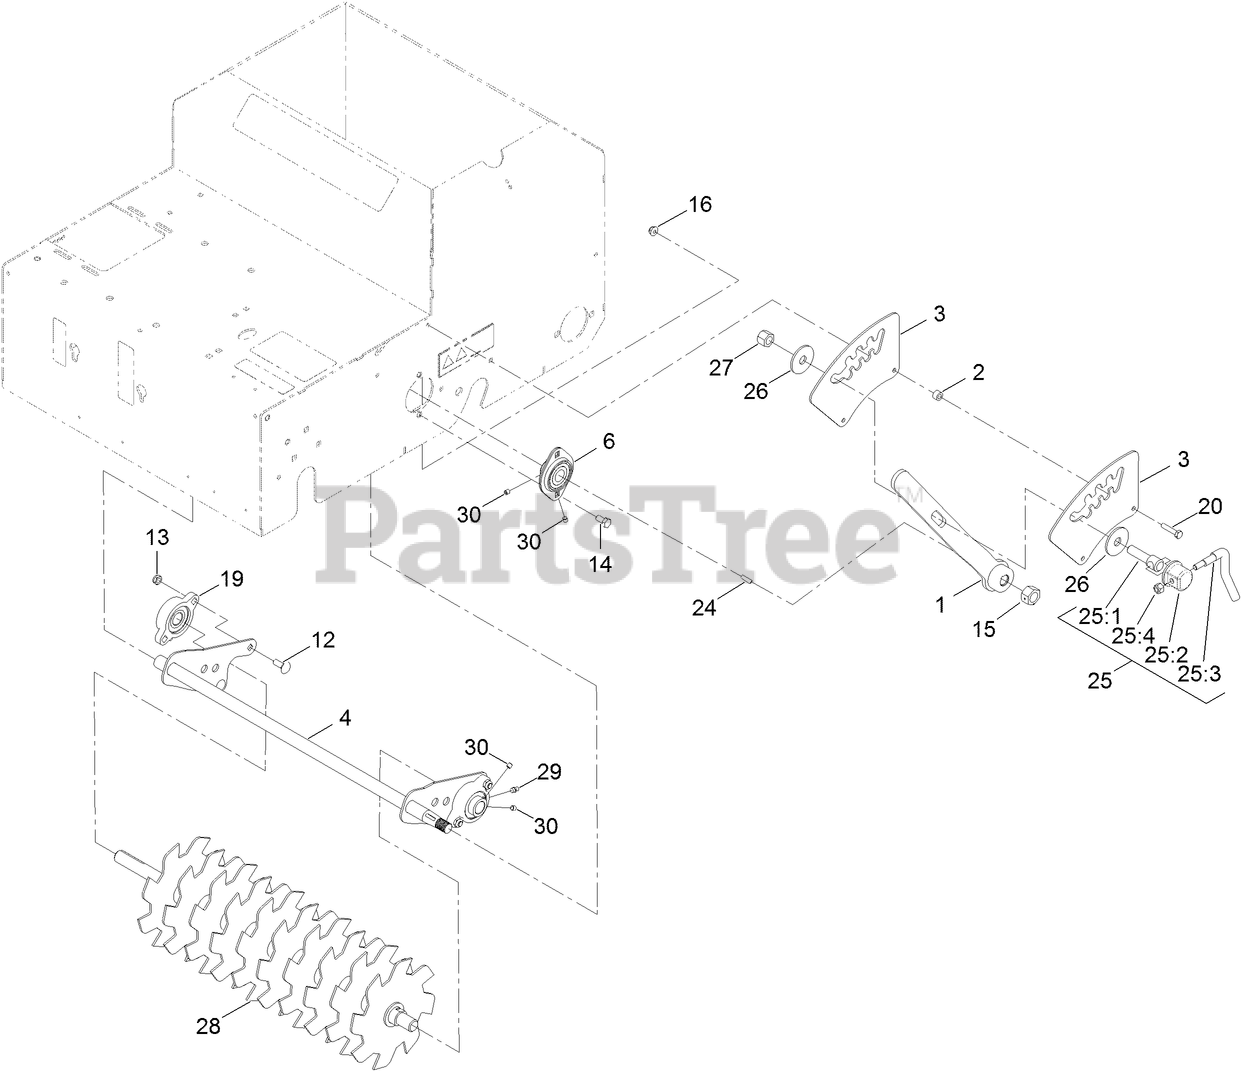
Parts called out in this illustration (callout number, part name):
1	HANDLE-HEIGHT
2	SPACER
3	PLATE-HEIGHT
4	PIVOT-HEIGHT
6	BEARING
12	SCREW-CARR
13	NUT-LOCK, NI
14	SCREW-HH
15	NUT-BLADE
16	NUT-HF
19	BEARING-FLANGE
20	SCREW-HH
24	KEY-WOODRUFF
25	LEVER ASM
25:1	Screw-Lock
25:2	CAP-LOCK
25:3	Lever-Lock
25:4	NUT-LOCK, NI
26	WASHER-THRUST
27	NUT-LOCK, NI
28	SLICER SHAFT ASM
29	FITTING-GREASE
30	SCREW-SET, HSH
